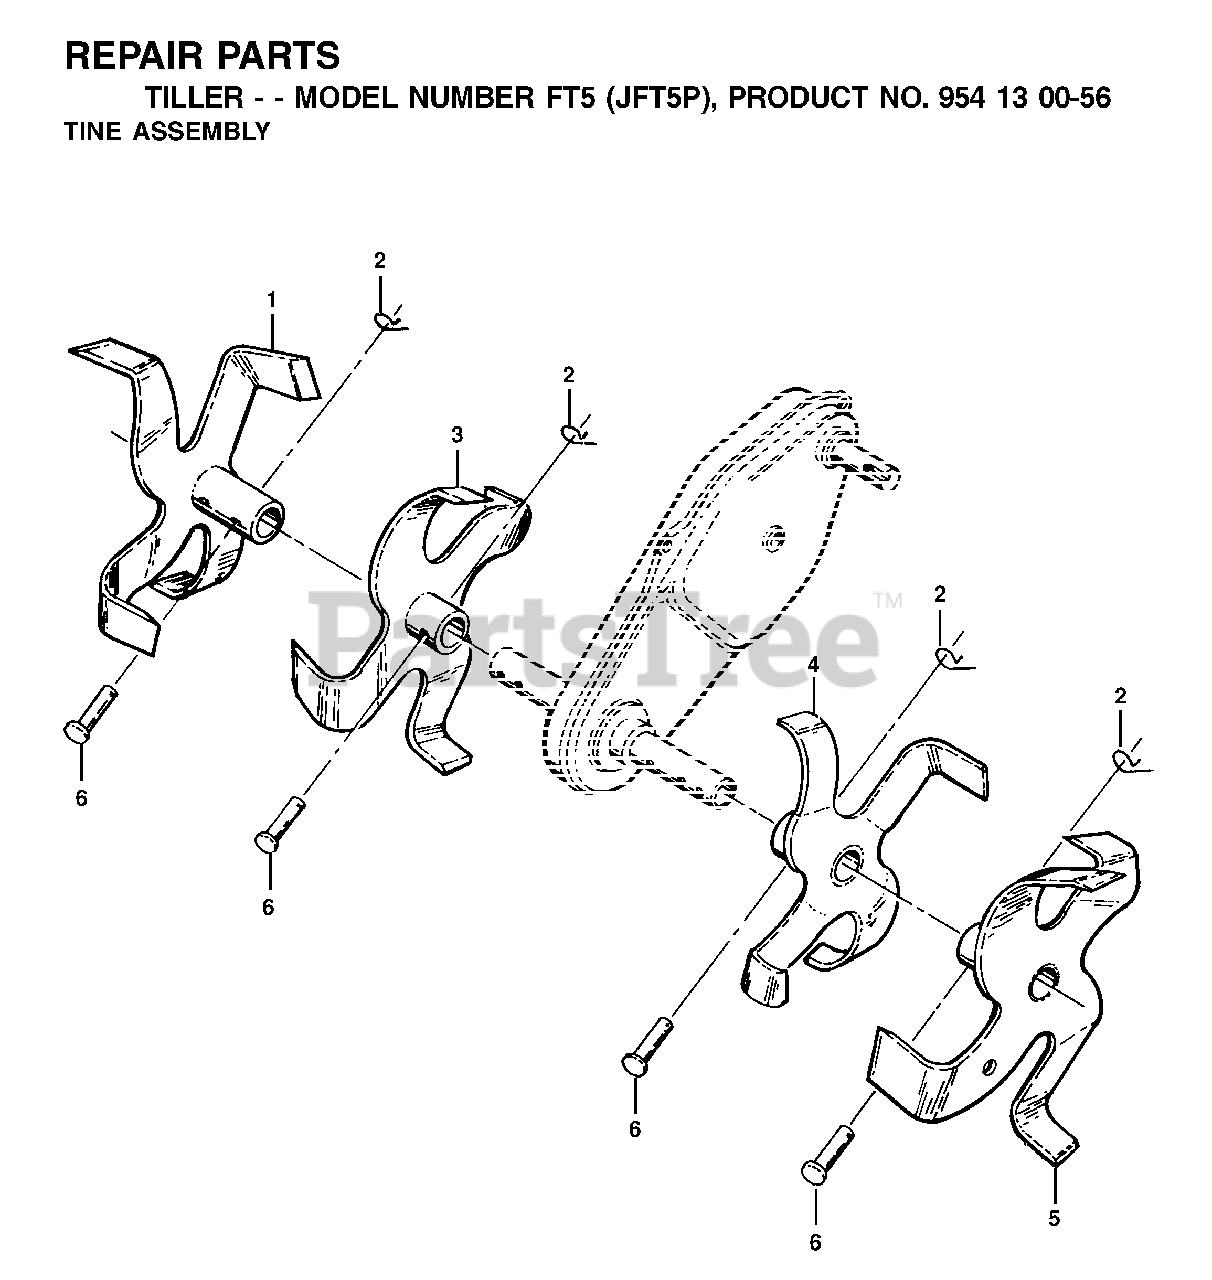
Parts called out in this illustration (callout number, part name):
1	RP TINE
2	SPRING RETAINER
3	RP TINE
4	RP TINE
5	RP TINE
